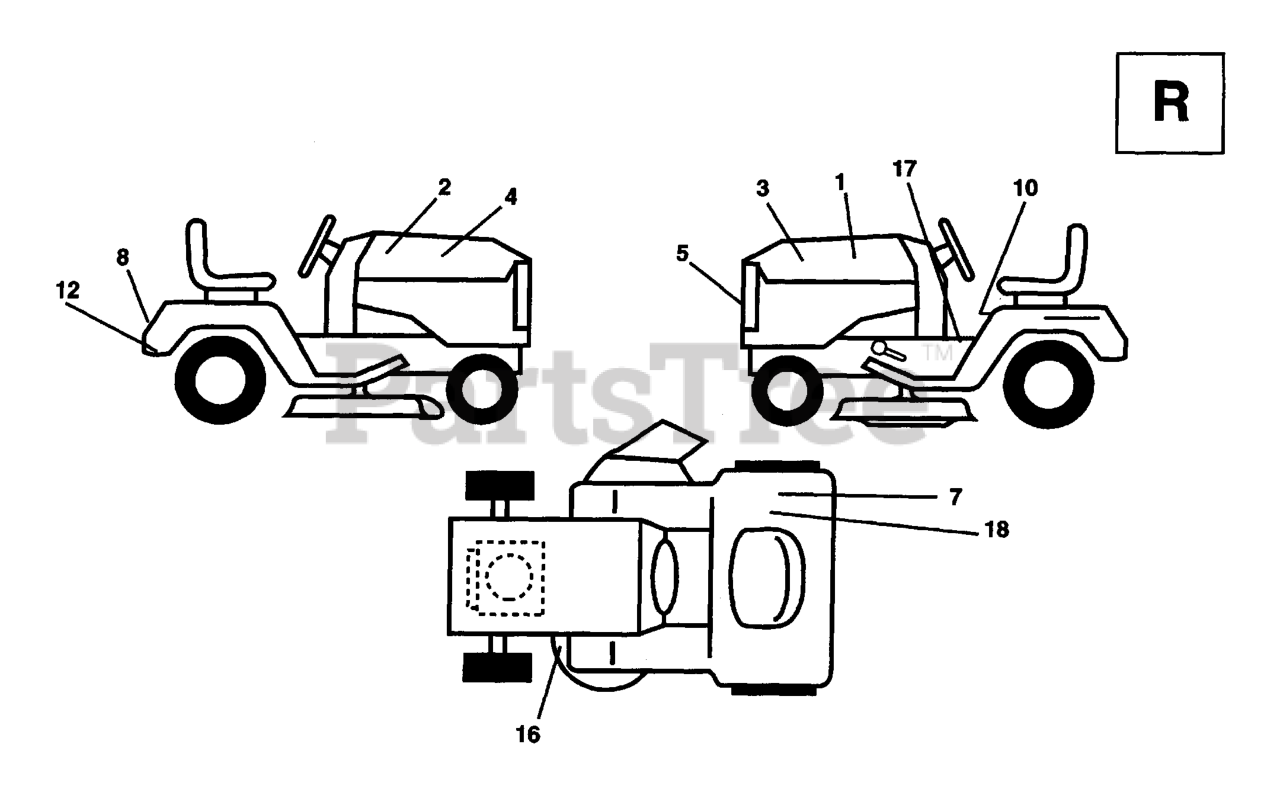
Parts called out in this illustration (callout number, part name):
1	HOOD DECAL LH
2	HOOD DECAL RH
5	DECAL-GRILL
7	DECAL CERTIFICATION
8	DECAL FENDER NLA
